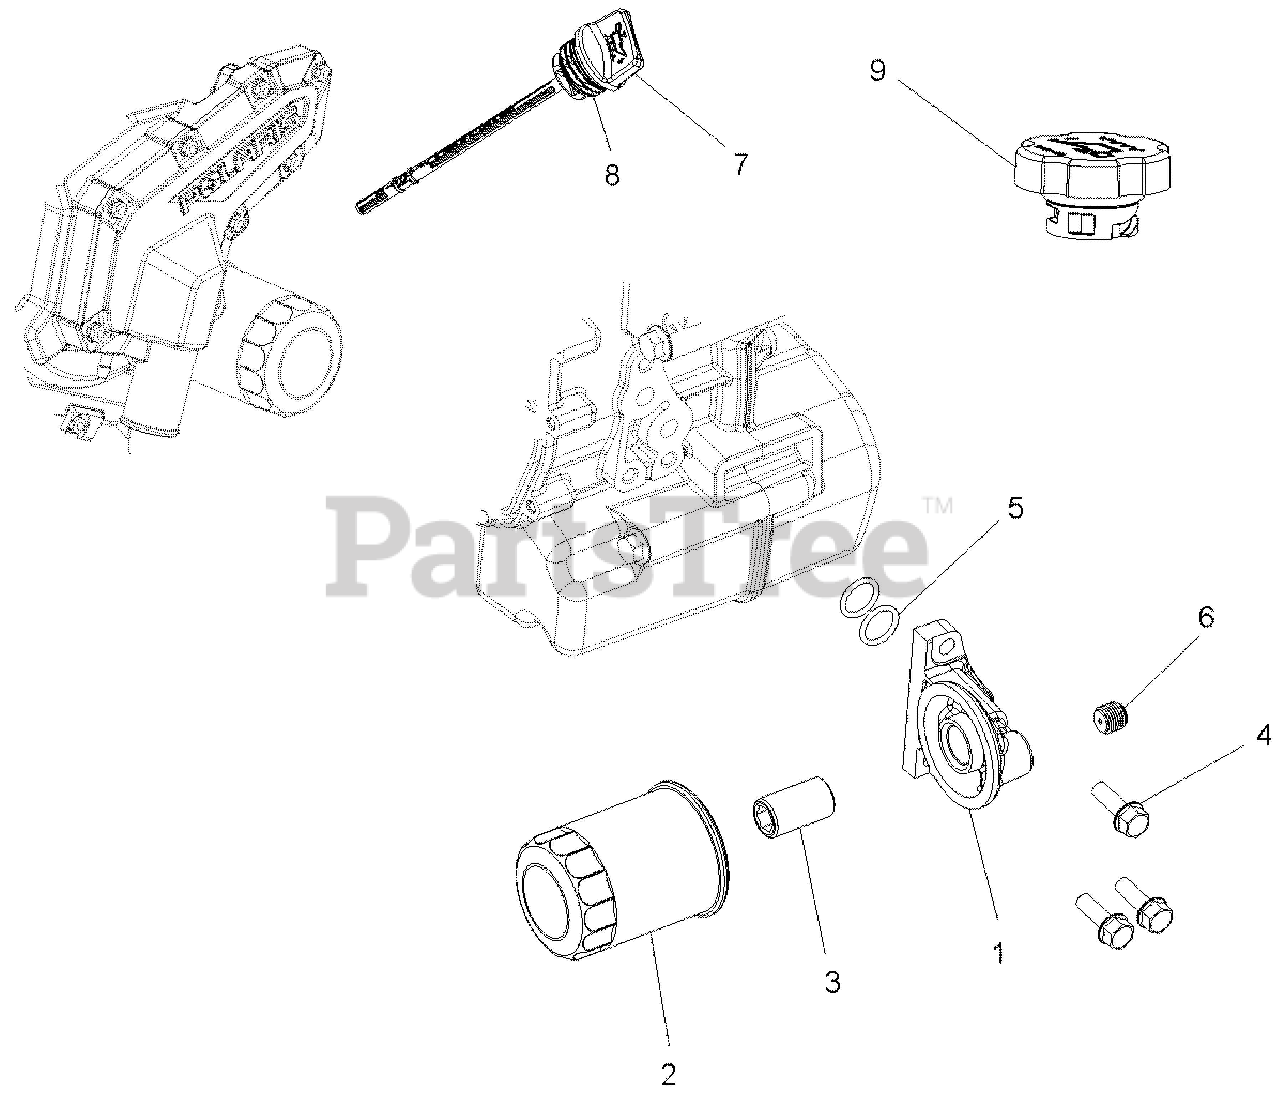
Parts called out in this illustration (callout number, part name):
1	ADAPTER-OIL FILTER,MACH
2	FILTER-OIL,10 MICRON,(12)
3	ADAPTOR, FILTER, STRAIGHT
5	O-RING-17.12X2.62
6	PLUG-HEX SOCKET,1/4X18,SEALANT
7	DIPSTICK-OIL FILL
8	O-RING-26.65X2.62,0600083
9	ASM-OIL FILL CAP
9	O-RING-FILL CAP
